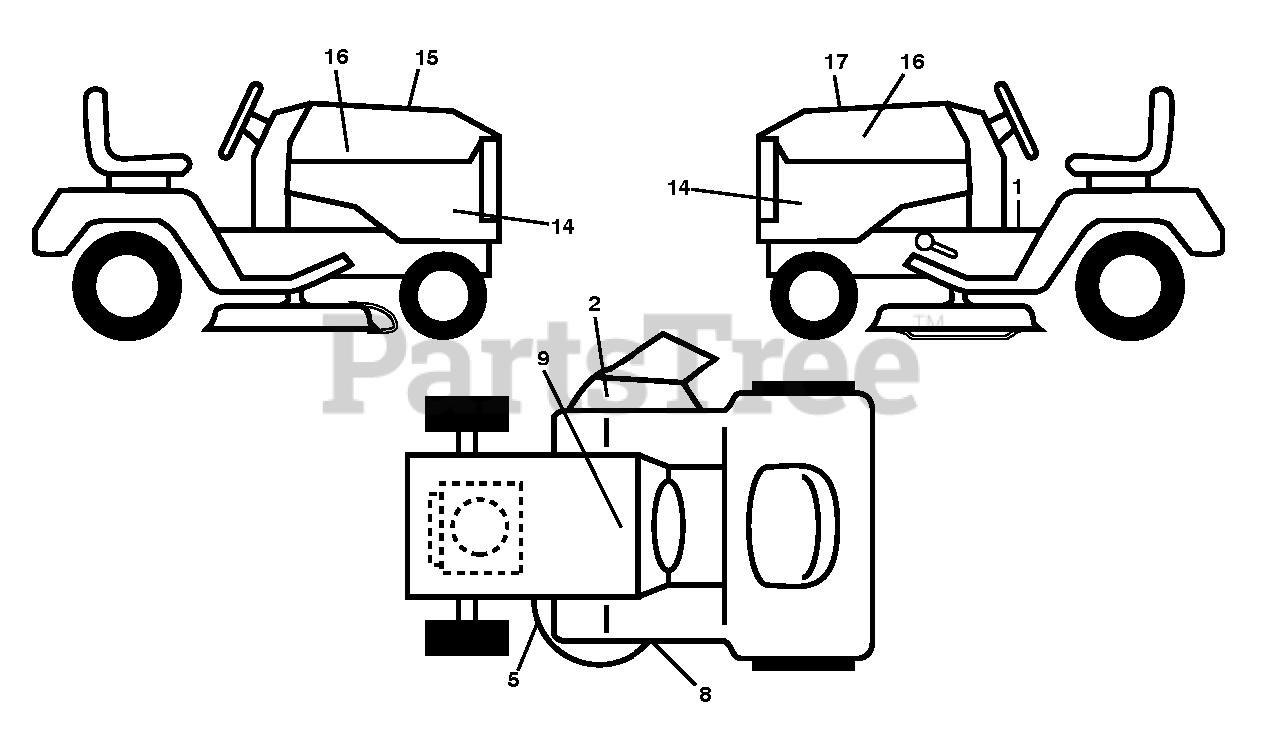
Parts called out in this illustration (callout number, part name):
1	DECAL.FENDER.WARNING
2	DECAL.WARN.KEEP.HAND.AWAY
5	DECAL.MOWER
8	DECAL.MOWER.SCH.48/54
9	DECAL BTRY SYMBOLS
14	DECAL.SIDE.PANEL.YTH24K48
15	DECAL.WARNING.CUST.RESP.E85.
16	RP.DECAL.BADGE.170MM.TEXTLOGO
